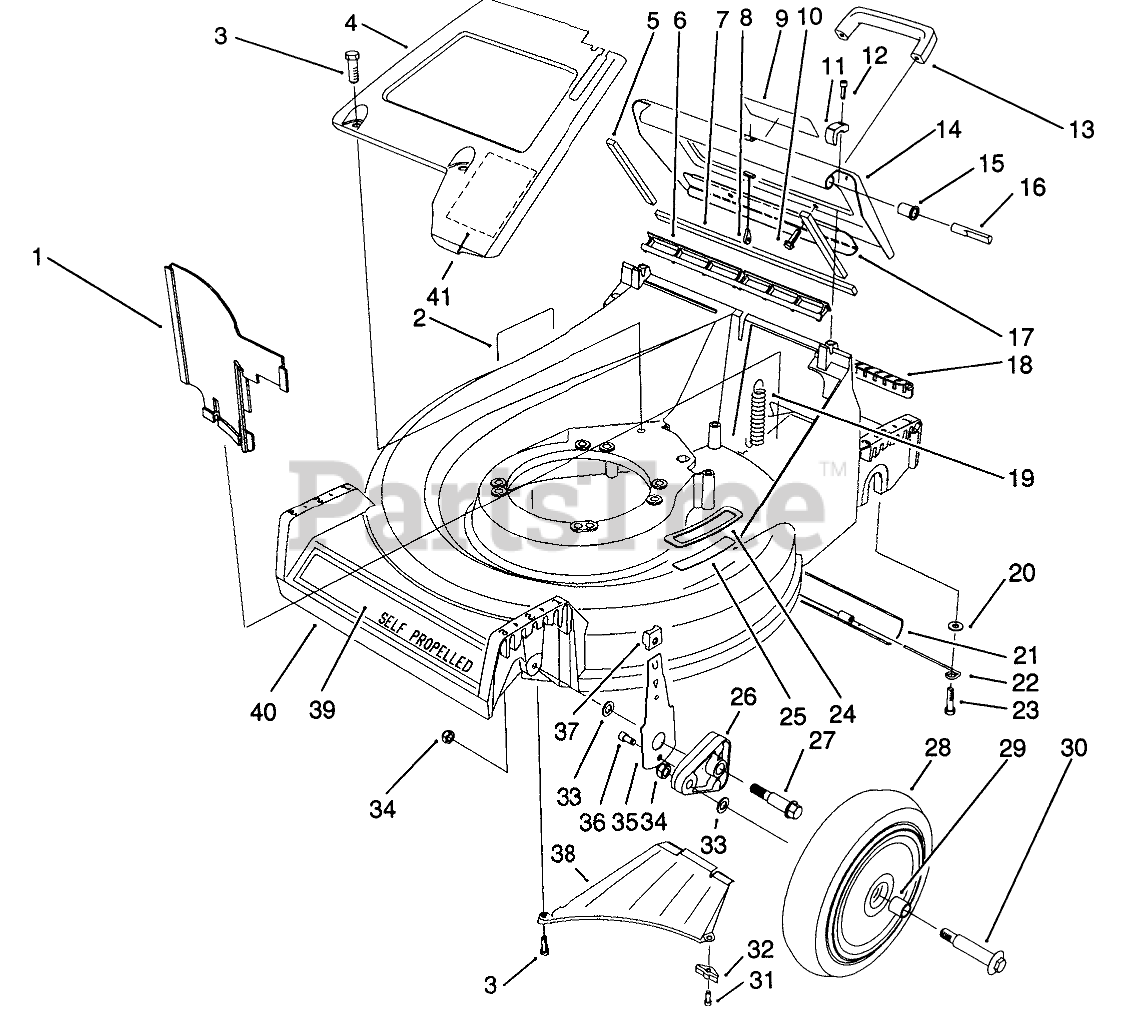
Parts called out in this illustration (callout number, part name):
1	PANEL-VERTICAL
2	DECAL-DANGER
3	SCREW-HWHTF
4	PaneI-Screen
5	DOOR SIDE SEAL
6	DOOR SEAL
7	DOOR END SEAL
8	DOOR CABLE
9	DECAL - WARNING
10	SCREW-HWH
11	HINGE CLAMP
12	SCREW-HSH
13	HANDLE-DOOR
14	Door-Discharge (Incl. Ref. #5, 7, 9, &17)
15	DOOR BUSHING
16	HINGE PIN
17	DOOR - BRACE
18	ACCESS COVER
19	EXTENSION-SPRING
20	WASHER-PLAIN
21	TRAILING SHIELD
22	SHIELD HANGER
23	SCREW-SHOULDER
24	STEP PAD
25	STEP PAD DECAL
26	ARM-PIVOT, FRONT
27	BOLT-SHOULDER
28	Wheel & Tire Assembly (Incl. Ref. #29)
29	BUSHING
30	WHEEL BOLT
31	SCREW-HWHTF
32	Bracket-Discharge
33	WASHER
34	NUT-LOCK
35	FRONT SPRING ARM ASM
36	SCREW-HSH, THREAD FORMING
37	KNOB-ARM
38	Ramp Discharge
39	DECAL - 21 SP
40	Housing-Deck (Incl. Ref. #2, 24, & 25)
41	DECAL - BBC ADJUST
